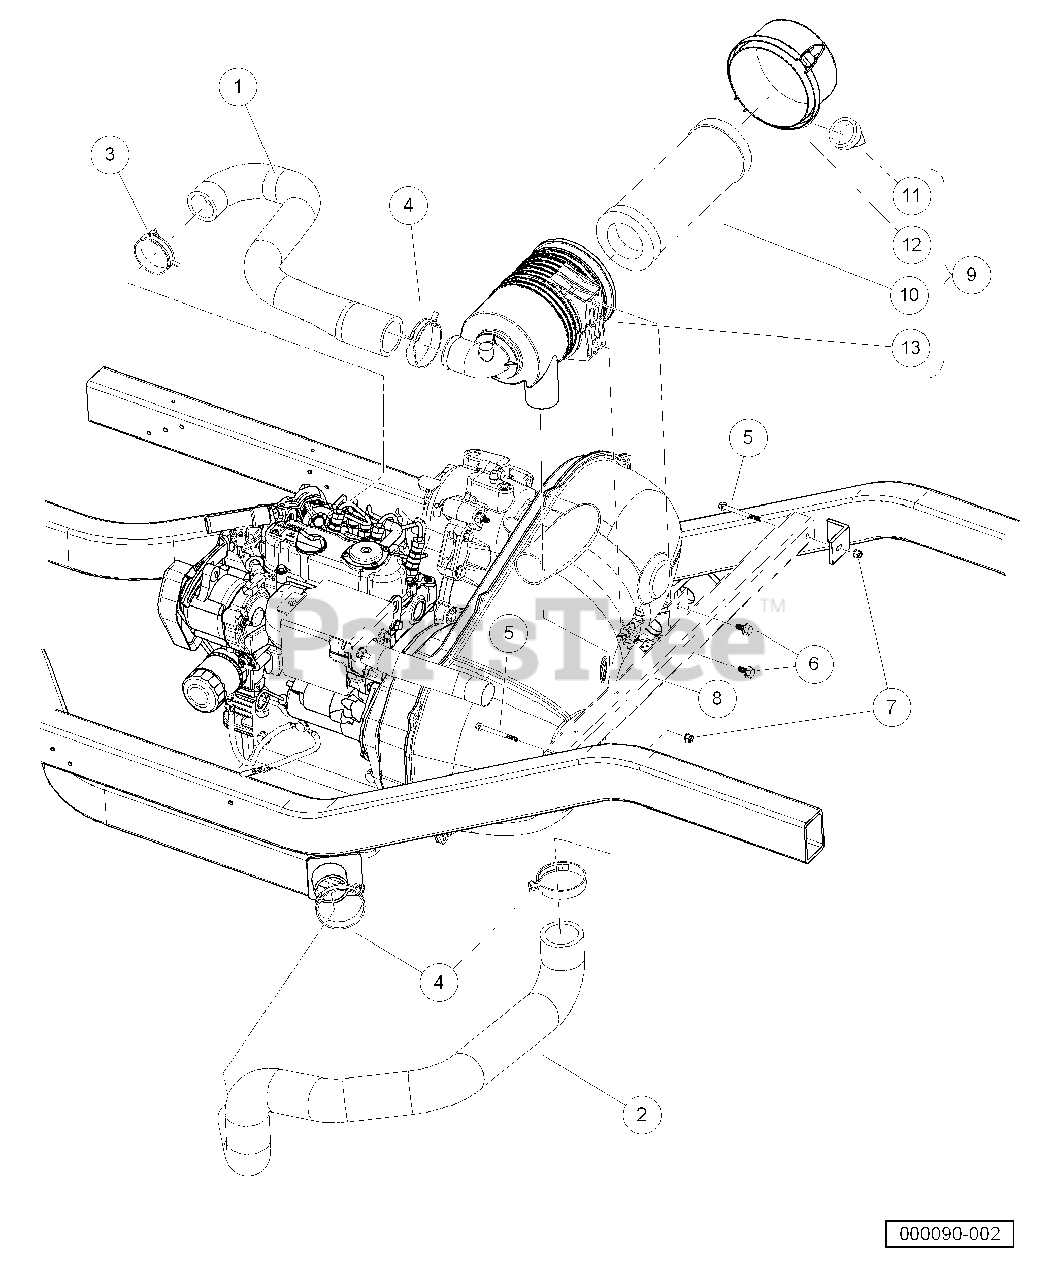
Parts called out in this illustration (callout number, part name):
1	Hose, Intake, D722
2	Hose, Intake, Primary
3	Clamp, Hose, Ctb 55mm
4	Clamp, Hose, Ctb 64mm
5	Bolt, M 6 X 1.0 X 65 Hex, Flange, Head, Black
6	Bolt Flanged Head, M8 X1.25x 16 with Loctite
7	Nut Flg, M6 X 1.0 Nylon
8	Weldment, Support, Air Cleaner
9	Filter, Air, Canister, W/labe
10	Element, Filter, Air, 5 In
11	Valve, Evacuator, Filter Air
12	Cap, Latch Lock, Filter, Air
13	Body, Canister, Filter, Air
